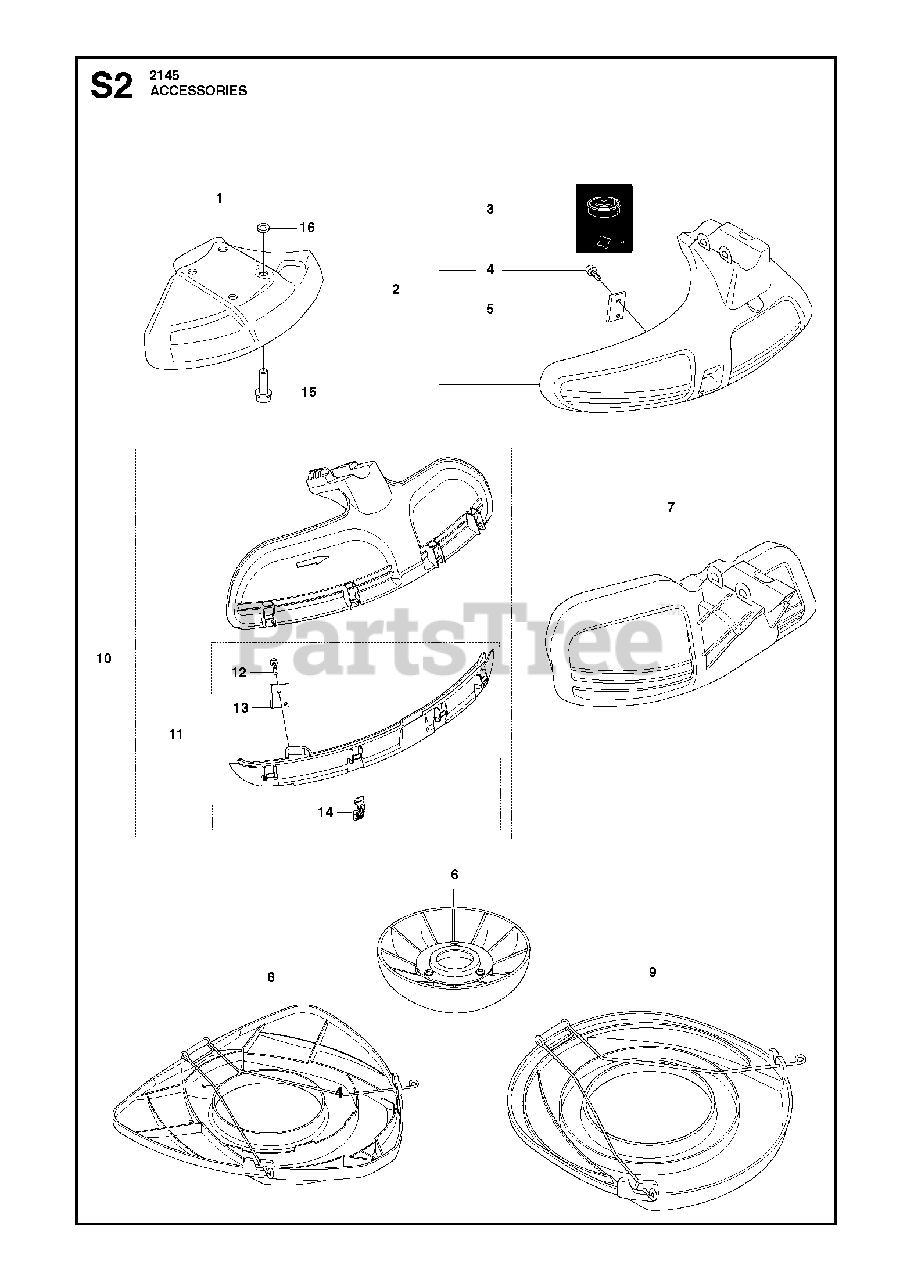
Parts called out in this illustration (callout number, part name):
1	BLADE GUARD
2	TRIMMER GUARD W/ CUTTER
3	DECAL
4	SCREW
5	LINE CUTTER
6	SUPPORTING CUP
7	PROTCTOR
8	TRANSPORT GUARD
9	BLADE GUARD TRANSPORT
10	COMBINATION GUARD
12	SCREW
13	LINE CUTTER
14	BUCKLE
16	LOCKING NUT
